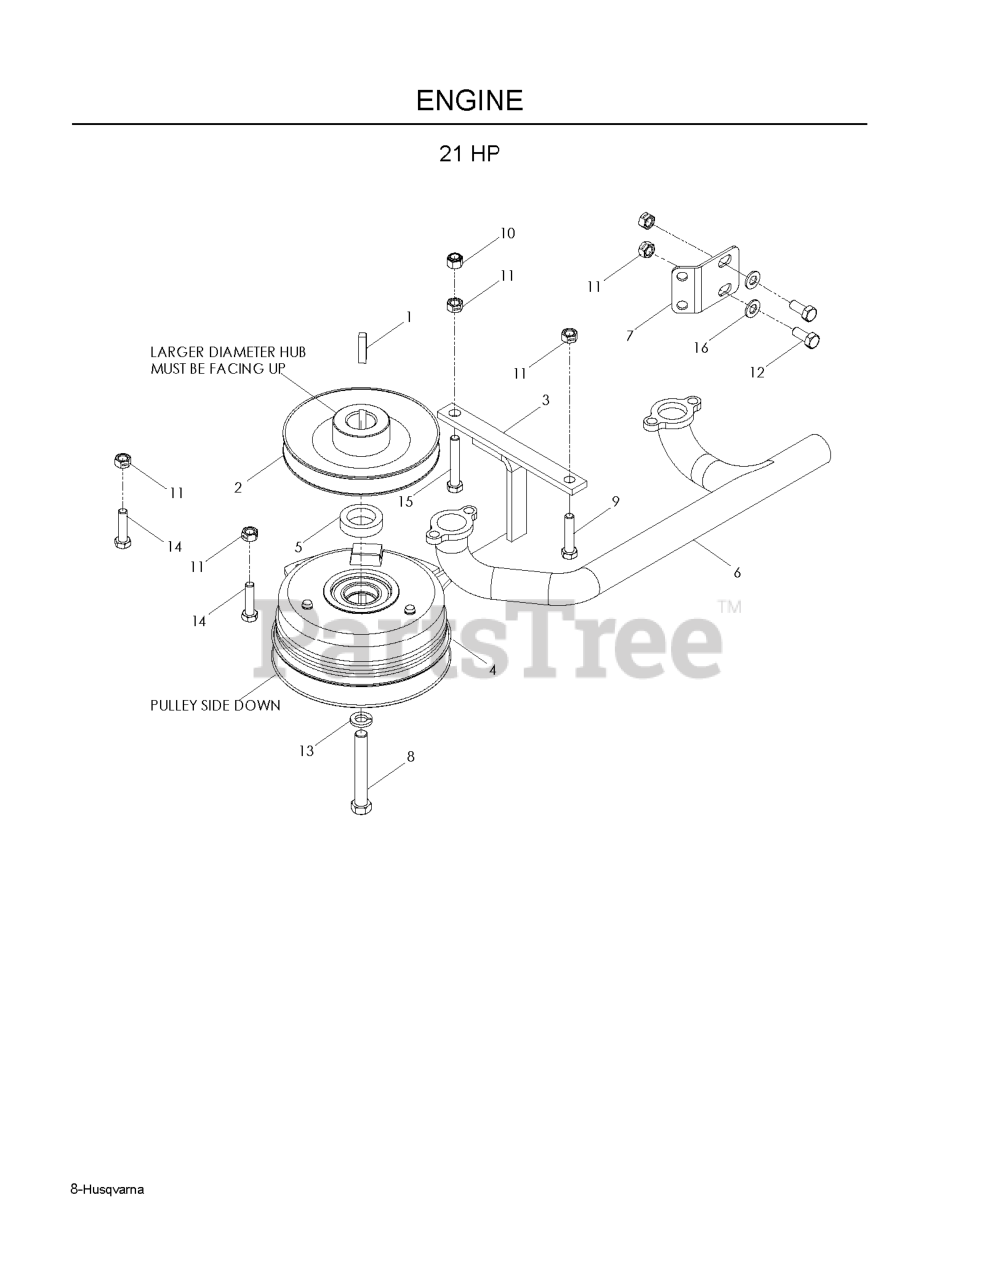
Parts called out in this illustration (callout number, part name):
1	KEY 1/4 SQ X 1 1/8
3	CLUTCH TIE DOWN
4	CLUTCH 125 FT/LB
6	MANIFOLD-EXHAUST, 21HP KAW
7	BRACKET-MUFFLER, BLK
8	HEX SCREW 7/16-20 X 3
9	CAPSCREW 5/16 X 1/1/2 HEX HEAD
10	NUT 5/16 NYLOC
11	NUT 5/16C CENTERLOCK
12	SCREW 5/16C X 1 HEX CAP
13	WASHER 7/16 LOCK
14	HCS 5/16C X 1 1/4
15	HCS 5/16-18X2
16	FLAT WASHER 5/16 SAE
